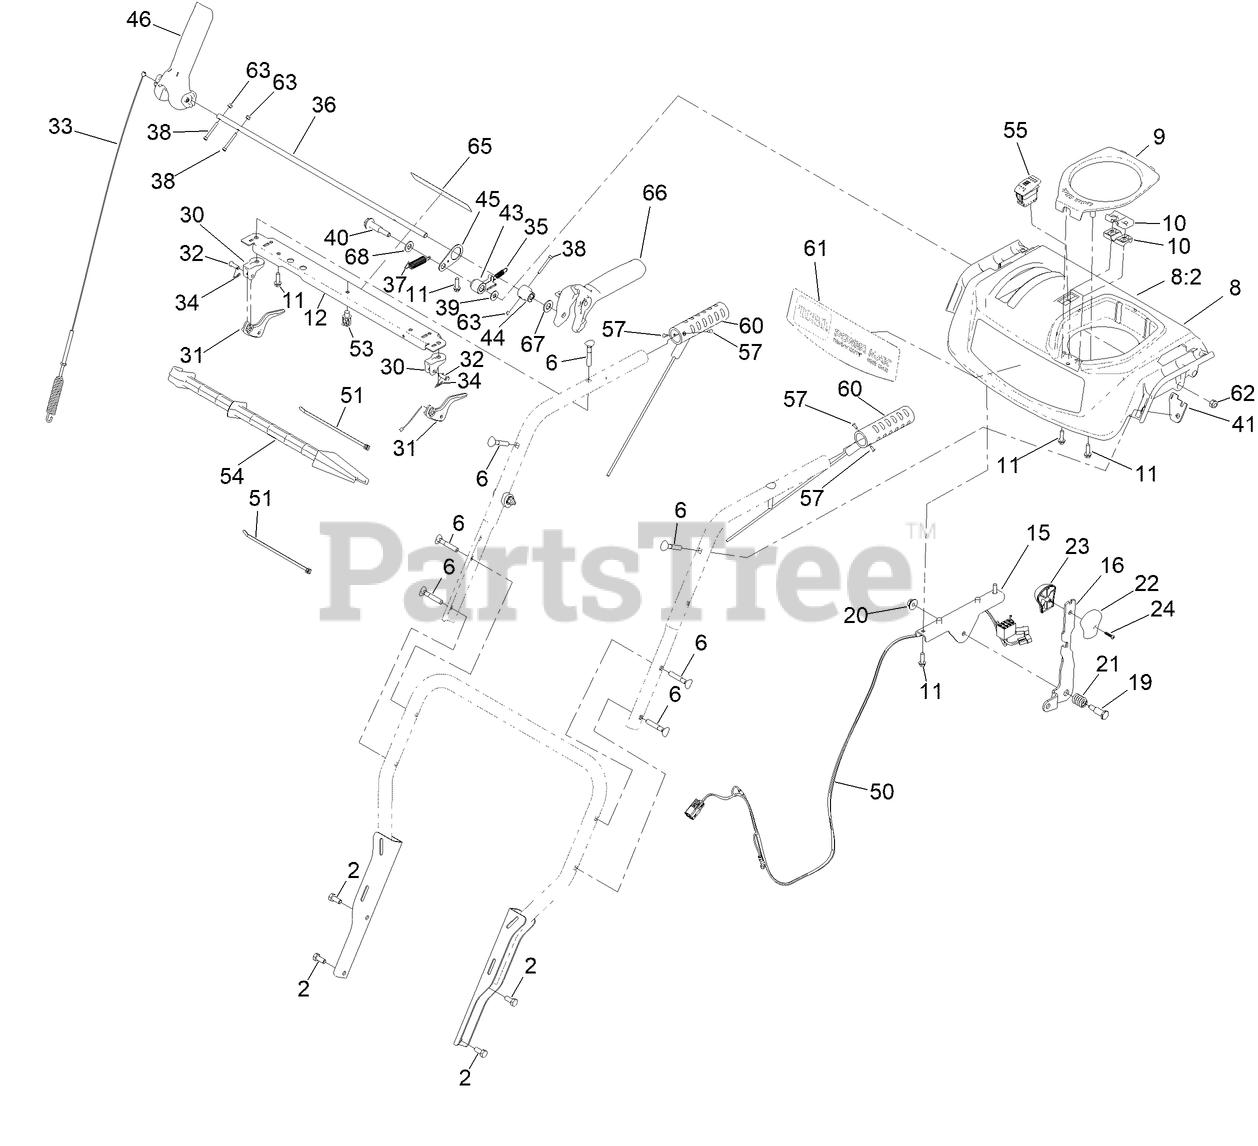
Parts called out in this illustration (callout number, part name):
2	SCREW-HH
6	SCREW-HANDLE
8	PANEL-CONTROL, ASSEMBLY
8:2	DECAL-SAFETY
9	COVER-QUICKSTICK
10	SUPPORT-ROD
11	SCREW-PLASTITE, HWH
12	BRACE-CONSOLE
15	BRACKET-SHIFT
16	SELECTOR-SPEED
19	SCREW-SHOULDER, HH
20	NUT-HF
21	SPRING-COMPRESSION
22	KNOB-SHIFT, LH
23	KNOB-SHIFT, RH
24	SCREW-PPH
30	MOUNT-LEVER, CLUTCH
31	LEVER-CLUTCH
32	PIN-CLEVIS
33	CABLE-AUGER
34	PIN-HAIR
35	SPRING-LOCKOUT, HANDLE
36	ROD-LOCKOUT
37	SPRING-RETURN, LEVER
38	SCREW-HSH,SPL
39	WASHER-FLAT
40	SCREW-SHOULDER
41	PLATE-SPRING
43	LATCH, LOCKOUT
44	CAM-LOCKOUT
45	LINK-LOCKOUT
46	LEVER-CONTROL
50	HARNESS-WIRE, LED AND HAND WARMERS
51	TIE-CABLE
53	CLIP-TIE
54	STICK-CLEANOUT
55	SWITCH-ROCKER, ON-NONE-OFF (HEATER)
57	RIVET-POP
60	RED HEATED GRIP
61	DECAL-CONSOLE
62	NUT-HEX
63	NUT-LOCK ROHS
65	DECAL-HYDRO
66	LEVER-CONTROL
67	WASHER-FLAT
68	WASHER-FLAT
